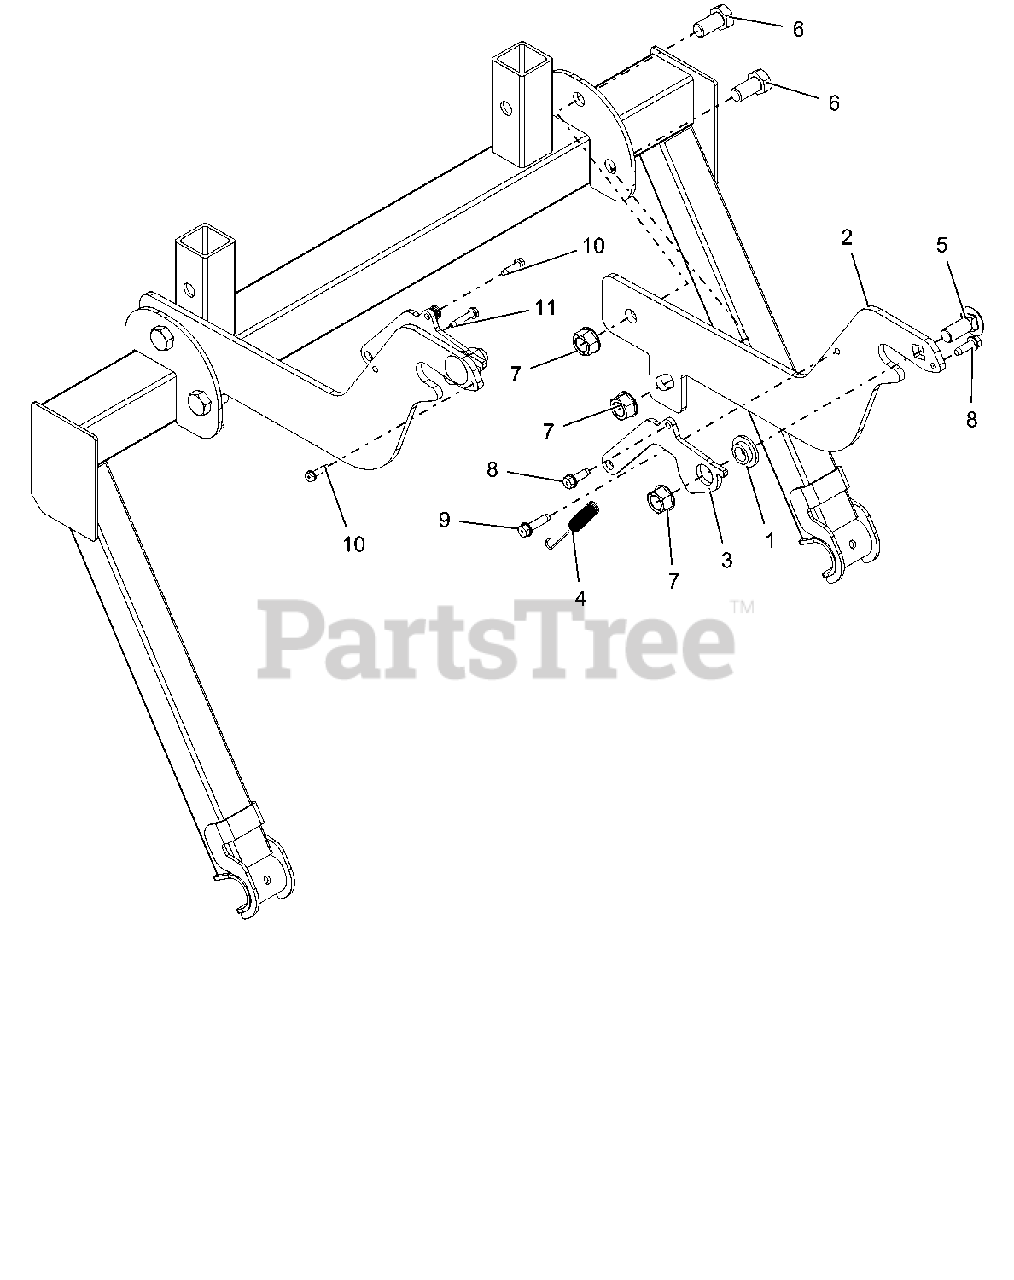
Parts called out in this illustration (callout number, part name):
1	BSHG-FLG .515X.750X.310X1.120
2	LATCH, ARM - BLACK
3	BAGGER, LATCH - BLACK
4	SG-TENS .043X.44X3.31 WLD 5.8
5	@BLT-RDHDSQNK .50-13X1.25 G5YZ
6	@BLT-HEX .50-13X1.00 GR5 YWZC
7	@NUT-LK-TOP-FLG .50-13 YWZC
8	SCR-TAP-PM .25-20X.75 TR YWZ
9	@SCR-TAP .25-20X1.00 HWH TR YZ
10	SCR-TAP 10-24X.75 HWH TR YWZC
11	@SCR-TAP 10-24X1.00 HWH TRYWZC
